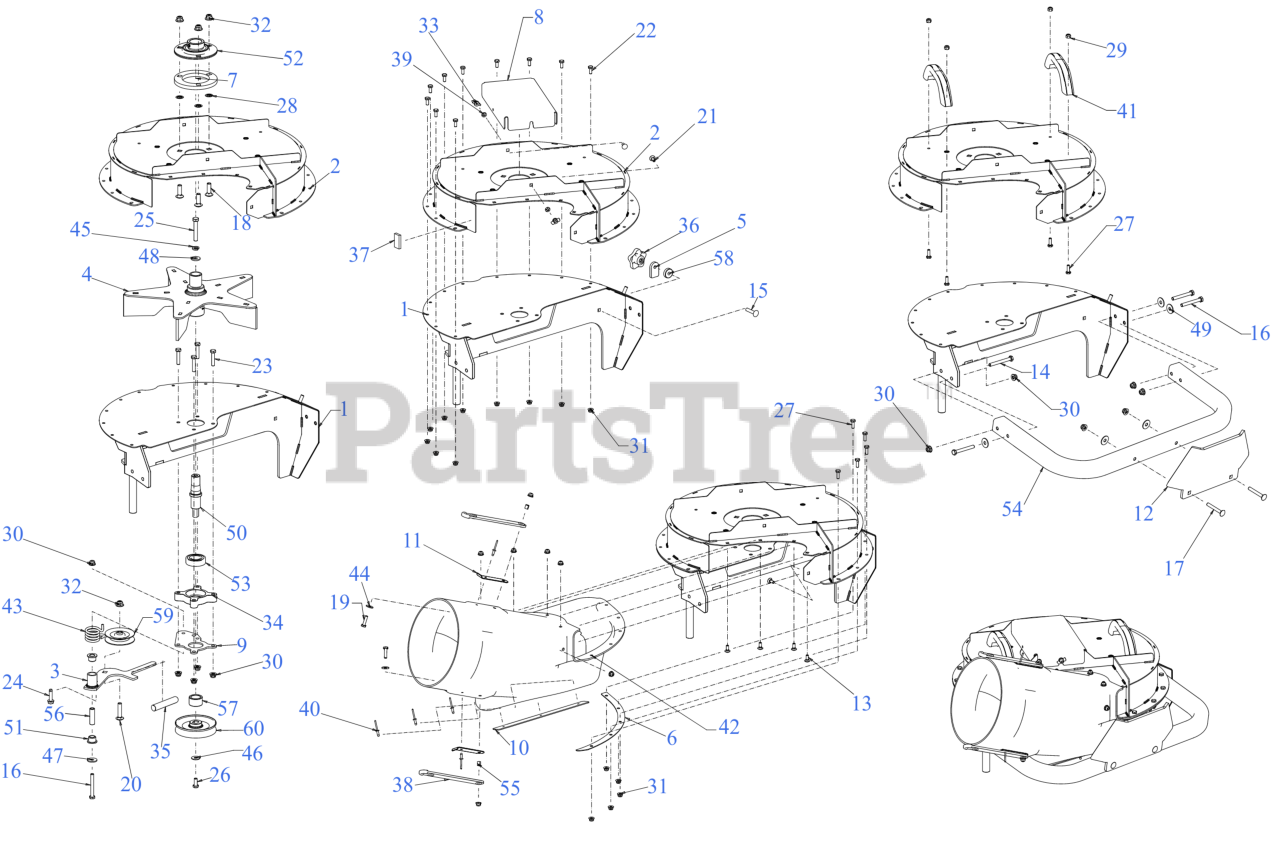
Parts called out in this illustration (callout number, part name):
1	BLOWER FRAME
2	IMPELLER HOUSING
3	IDLER ASSEMBLY
5	BLOWER LATCH PLATE
6	HOUSING PLATE
7	BLOWER BEARING PLATE
8	SHAFT COVER
9	IDLER MOUNT PLATE
10	GUARD PLATE
11	CHUTE STOP BRACKET
12	BRACKET GUARD
13	CARRIAGE BOLT 1/4-20 x .62
14	HEX SCREW 5/16-18 x 2.75
15	CARRIAGE BOLT 5/16-18 x 1.50
16	SCREW 5/16-18 x 2.5 GR 5
17	BOLT 5/16-18 x 2.50 GR1
18	CARRIAGE BOLT 3/8-16 X1.25 GR5
19	SCREW 1/4-20 X1.00 GR5
20	BOLT 3/8-16 x 1.69 GR5
21	SCREW 1/4-20 x .75 GR5
22	SCREW 1/4-20 x .620 GR5
23	SCREW 5/16-18 x 1.5 LG
24	SCREW 5/16-18 x 1.25
25	SCREW 3/8-24X2.25 GR8
26	SCREW 5/16-18 x .750
27	SCREW 1/4-20X.75 GR5
29	NYLON LOCK NUT
30	FLANGE LOCK NUT 5/16-18
31	FLANGE LOCK NUT
33	WING NUT 1/4-20
34	BEARING HOUSING
35	FOAM GRIP
36	STAR KNOB- YELLOW
37	FOAM TAPE .75" WIDE x .25" THICK
38	CHUTE STRAP
39	RETAINER-BOLT .25ID x .50OD
40	RIVET - 3/16"
41	GRAB HANDLE
42	BLOWER CHUTE
43	TORSION SPRING
44	FLAT WASHER .28 ID x .74 OD x .063
45	LOCK WASHER 3/8HD
46	FLAT WASHER
47	FLAT WASHER 1.0 OD:.331 ID
49	FLAT WASHER 344X1.00
50	IMPELLER SPINDLE SHAFT
51	FLANGE BEARING
52	FLANGE BALL BEARING (3-BOLT)
53	BALL BEARING
54	BUMPER TUBE
55	SPLIT SPACER
56	SLEEVE .33X.50X1.73 LG
58	SPACER 0.325x1.0x0.312
59	V-IDLER PULLEY A x 3.06 OD
